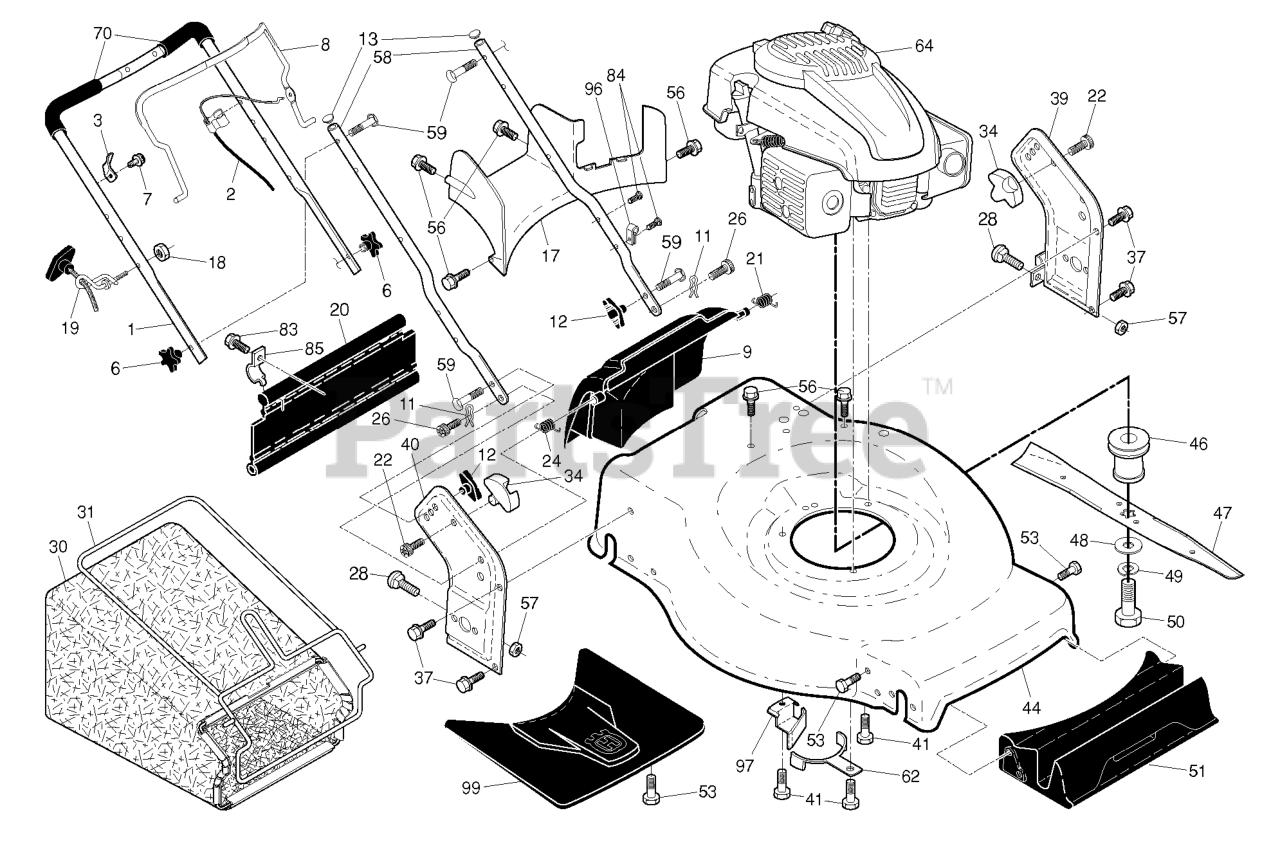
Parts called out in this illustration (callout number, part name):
1	FUEL.TANK.ASM.LH.PZ.REFRESH.18
2	FUEL.TANK.ASM.RH.PZ.REFRESH.18
3	HOSE.3/16".VAPOR.LINE.50"LGTH
4	HOSE.3/16".VAPOR.LINE.26"LGTH
5	HOSE.3/16".VAPOR.LINE.17"LGTH
6	HOSE.1/4".LOW.PERM.FUEL.LN.46"
7	HOSE.1/4".LOW.PERM.FUEL.LN.33"
8	HOSE.1/4".LOW.PERM.FUEL.LN.24"
9	TEE, FUEL LINE 3/16"
10	CAP, FUEL
11	GUARD.MUD.LH
12	SENSOR.FUEL.LVL.FLOAT.V500
13	VALVE.FUEL.CHECK
14	FUEL VALVE
15	TUBE.ASM.FUEL.TANK.PICK-UP.LH
16	BUSHING OUTLET T
17	GROMMET, FUEL SENSOR
18	GROMMET.CHECK.FUEL
19	BRACKET.FUEL.TANK.REAR.SUP.431
20	BRACKET.FUEL.TANK.REAR.SUP.431
21	COVER.LH.FUEL.TANK/CONSOLE APP
22	HOSE CLAMP
23	CLAMP, HOSE
24	CLIP.U-TYPE
25	TIE WRAP, 8-3/8", W/CLIP
26	BOLT HEX FLGHD 5/16-18X3 GR. 5
27	SCREW.1/4-20X1.5IN.HEX.MACH
28	SCREW
29	SCREW.5/16-18X1.25"THREADED
30	5/16-18 NYLOC FLANGE NUT
31	WASHER
